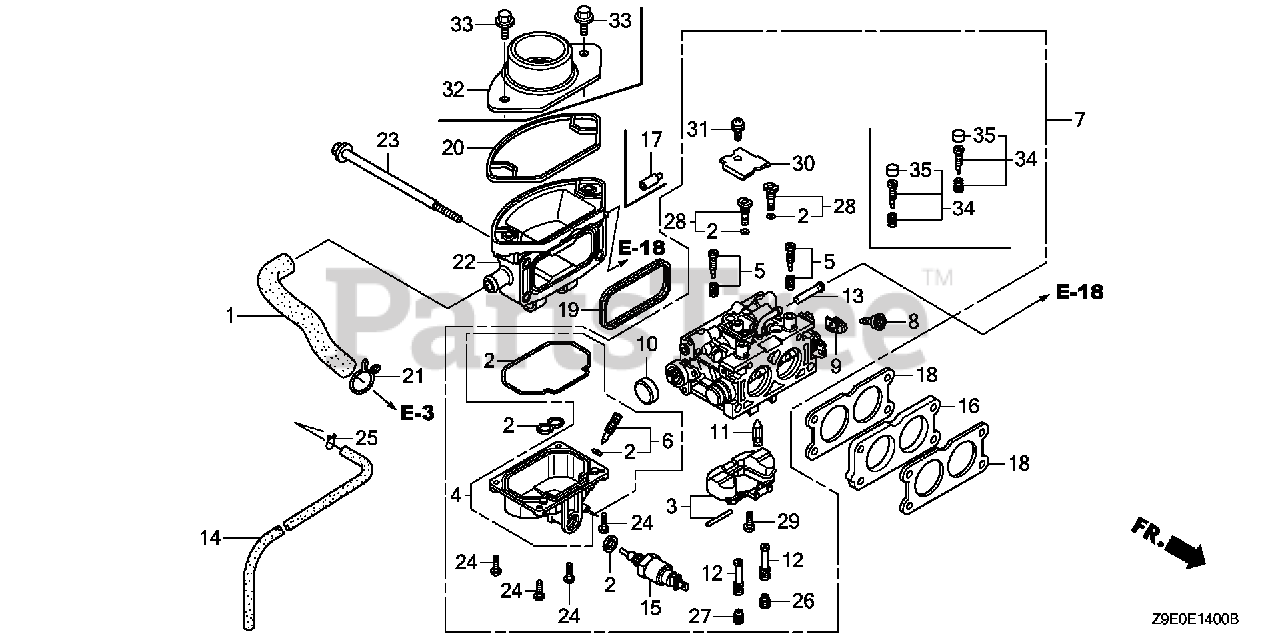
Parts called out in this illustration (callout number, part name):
1	TUBE, BREATHER
2	GASKET SET
4	CHAMBER SET, FLOAT
5	SCREW SET (CARBURETOR NO.)
6	SCREW SET, DRAIN
7	CARBURETOR ASSY. (BK07A C)
7	CARBURETOR ASSY. (BK07A D)
8	SCREW, THROTTLE STOP
9	ARM, THROTTLE LINKAGE
10	CAP, CHOKE DUST
11	VALVE, FLOAT
12	NOZZLE, MAIN (CARBURETOR NO.)
13	SCREEN, FUEL STRAINER
14	TUBE, DRAIN
15	VALVE ASSY., SOLENOID
16	INSULATOR, CARBURETOR
18	GASKET, CARBURETOR
19	GASKET, AIR CLEANER
20	SEAL, AIR CLEANER HOUSING
21	CLIP, BREATHER TUBE
22	ELBOW, AIR CLEANER
23	BOLT, FLANGE (6X106)
24	SCREW, PAN (4X12)
25	CLIP, TUBE (B8)
26	JET, MAIN (#90) (CARBURETOR NO.)
26	JET, MAIN (#95) (CARBURETOR NO.)
26	JET, MAIN (#98) (CARBURETOR NO.)
26	JET, MAIN (#102) (CARBURETOR NO.)
26	JET, MAIN (#110) (CARBURETOR NO.)
27	JET, MAIN (#92) (CARBURETOR NO.)
27	JET, MAIN (#98) (CARBURETOR NO.)
27	JET, MAIN (#102) (CARBURETOR NO.)
27	JET, MAIN (#105) (CARBURETOR NO.)
27	JET, MAIN (#110) (CARBURETOR NO.)
28	JET SET, PILOT (#40)
29	SCREW, FLOAT
31	SCREW-WASHER (5X10)
34	SCREW SET (CARBURETOR NO.)
35	CAP, ADJUSTING SCREW (CARBURETOR NO.)
